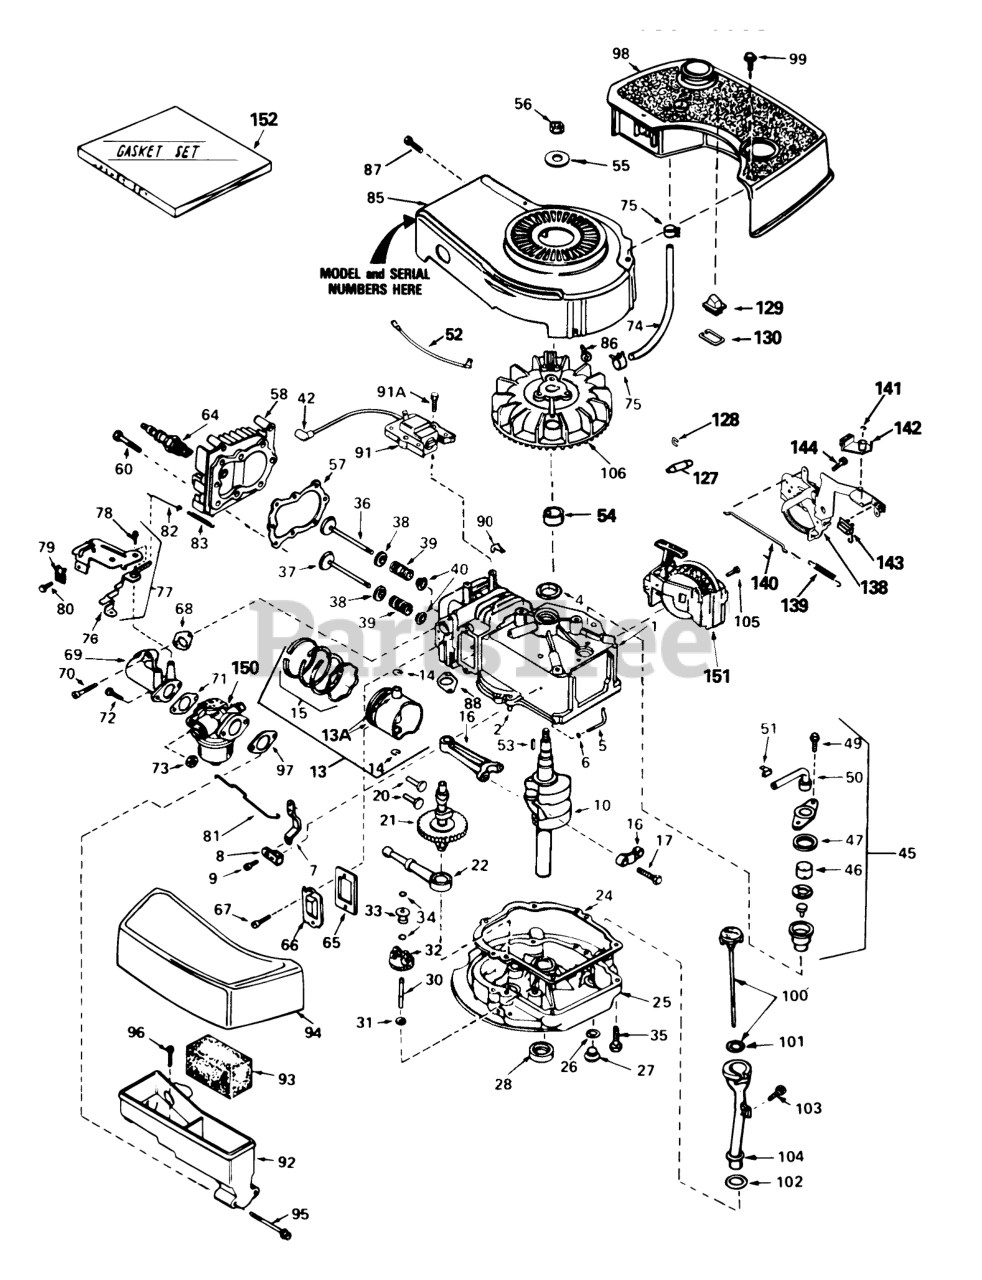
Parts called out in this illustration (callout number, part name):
1	Cylinder Assy. (Inc. #2 & 4)
2	Pin-Dowel
4	Seal-Oil
5	Rod, Governor (Incl. #6)
6	Washer-Flat
7	Governor Lever
8	Clamp-Lever, Governor
9	Screw
10	Crankshaft
13	Piston, Pin & Ring Assy. (Std.) (Incl. #13A, 14 & 15)
13	Piston, Pin & Ring Assy. (.010 oversize) (Incl. #13A, 14 & 15)
13	Piston, Pin & Ring Assy. (.020 oversize) (Incl. #13A. 14 & 15)
13A	Piston & Pin Assy. (Std.) (Inc. #14)
13A	Piston & Pin Assy. (.010 oversize) (Incl. #14)
13A	Piston & Pin Assy. (.020 oversize) (Inc. #14)
14	Ring-Retaining, Piston Pin
15	Ring Set (Std.)
15	Ring Set (.020" OS)
15	Ring Set (.010" OS)
16	Rod Assy., Connecting (Incl. #17)
17	Bolt-Rod, Connecting
20	Lifter-Valve
21	Camshaft(Mech.Comp. Release)
22	Oil Pump ASM
24	Gasket, Mounting
25	Flange Assy., Mounting (Incl. #26 thru 30)
26	Gasket-Oil Drain
27	Plug Oil Drain
28	Seal Oil
30	Shaft-Governor
31	Washer-Flat
32	Gear Assy., Governor (Incl. #31)
33	Spool-Governor
34	Ring-Retaining
35	Screw (1/4-20 x 1-1/4)
36	Valve, Intake (Std.) (Incl. #40)
36	Valve, Intake (1/32" oversize) (Incl. #40)
37	Valve, Exhaust (Std.) (Incl. #40)
37	Valve, Exhaust (1/32" oversize (Incl. #40)
38	Cap-Upper Valve Spring
39	Spring-Valve
40	Cap-Valve, Spring
42	Cover-Spark Plug
45	Breather Assy. (Incl. #46 thru 51)
46	Element-Breather
47	Gasket-Breather
49	Screw (10-24 x 9/16)
50	Tube, Breaker
51	Clip, Breather
52	Ground Wire
53	Key-Flywheel
55	Washer-Belleville
56	Nut-Flywheel
57	63573 GIL 42 SNWTHW
58	Head-Cylinder
60	Screw (5/16-18x1-1/2)
64	Plug, Spark (J17LM or equiv.)
64	Plug, Spark (Champion RCJ-8)
65	Gasket-Breather
66	Cover-Valve
68	Gasket-Intake
69	Pipe, Intake (Incl. #68)
70	Screw (1/4-20 x 1)
71	Gasket-Carburetor
72	Screw (1/4-28 x 7/8)
73	Nut and Lock Washer (1/4-28)
74	Line-Fuel
75	Clamp-Line, Fuel
76	Lever Control
77	Control Assy., Speed (Incl. #76 & 78)
78	Screw, Hex Washer Hd Shoulder Self-Tap
79	Conduit
80	Screw (10-32 x 3/8)
81	Link-Throttle
82	Link Governor Spring
83	Spring Governor
85	Housing-Blower
86	Screw (1/4-20x19/32)
87	Screw (10-24 x 9/16)
88	Gasket Exhaust
90	Clip-Wire
91	Lamination & Coil Assy. (Solid State) (Incl. #42)
91A	Screw
92	Body Air Cleaner
93	Filer, Air
94	Cove, Air Cleaner
95	Screw Fil Hd.
96	Screw, Hex Hd.
97	Gasket-Air Cleaner
98	Tank, Fuel
99	Screw (10-32 x 35/64)
100	Dipstick, Oil (Incl. #101)
103	Screw (10-32 x 1/2)
104	Tube-Oil Fill
105	Screw (1/2-20x5/8)
106	Flywheel
127	Coupling, Starter Rope
128	Staple, Rope Retainer (Strip of 25 Pieces)
129	Pulley Assy., Starter
130	Retainer, Pulley
138	Bracket Assy.
139	Spring-Extension
140	Link-Control
141	Ring-Retaining
142	Lever-Brake
143	Terminal
144	Screw-Hex. Hd.
150	Carburetor (Incl. #71)
151	Starter, Sidemount rewind
152	Gasket Set (Incl. Items Marked )
